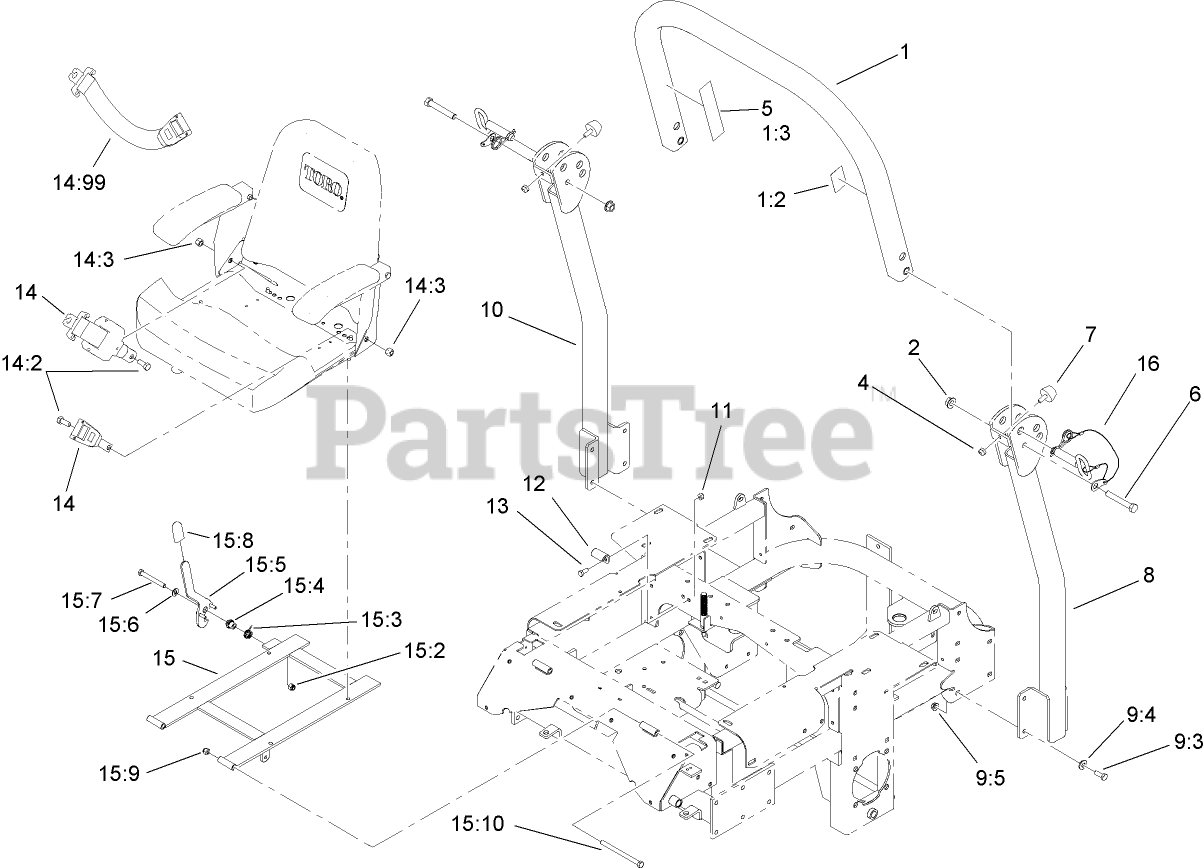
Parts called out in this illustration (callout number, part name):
1	Upper Tube ASM
1:2	DECAL-ROPS
1:3	DECAL-WARNING, FOLDING ROPS
2	NUT-HF
4	NUT-LOCK, NI
5	DECAL-WARNING
6	SCREW-HH
7	BUMPER-RUBBER
8	TUBE-SUPPORT, LH
9:3	SCREW-HH
9:4	WASHER-BELLEVILLE
9:5	NUT-HHF, WHIZ
10	TUBE-SUPPORT, RH
11	NUT-LOCK, NI
12	Catch-Latch, Seat
13	SCREW-HH
14	RETRACTABLE SEATBELT KIT
14:2	SCREW-HH
14:3	NUT-LOCK
14:99	SEAT BELT EXTENSION KIT
15	SEATFRAME ASM
15:2	NUT-LOCK, NI
15:3	SPRING-TORSION
15:4	BUSHING-LATCH, SEAT
15:5	LATCH ASM
15:6	WASHER-FLAT
15:7	SCREW-HH
15:8	GRIP-LEVER
15:9	NUT-LOCK, NI
15:10	SCREW-HH
16	PIN-FOLD, ROPS
